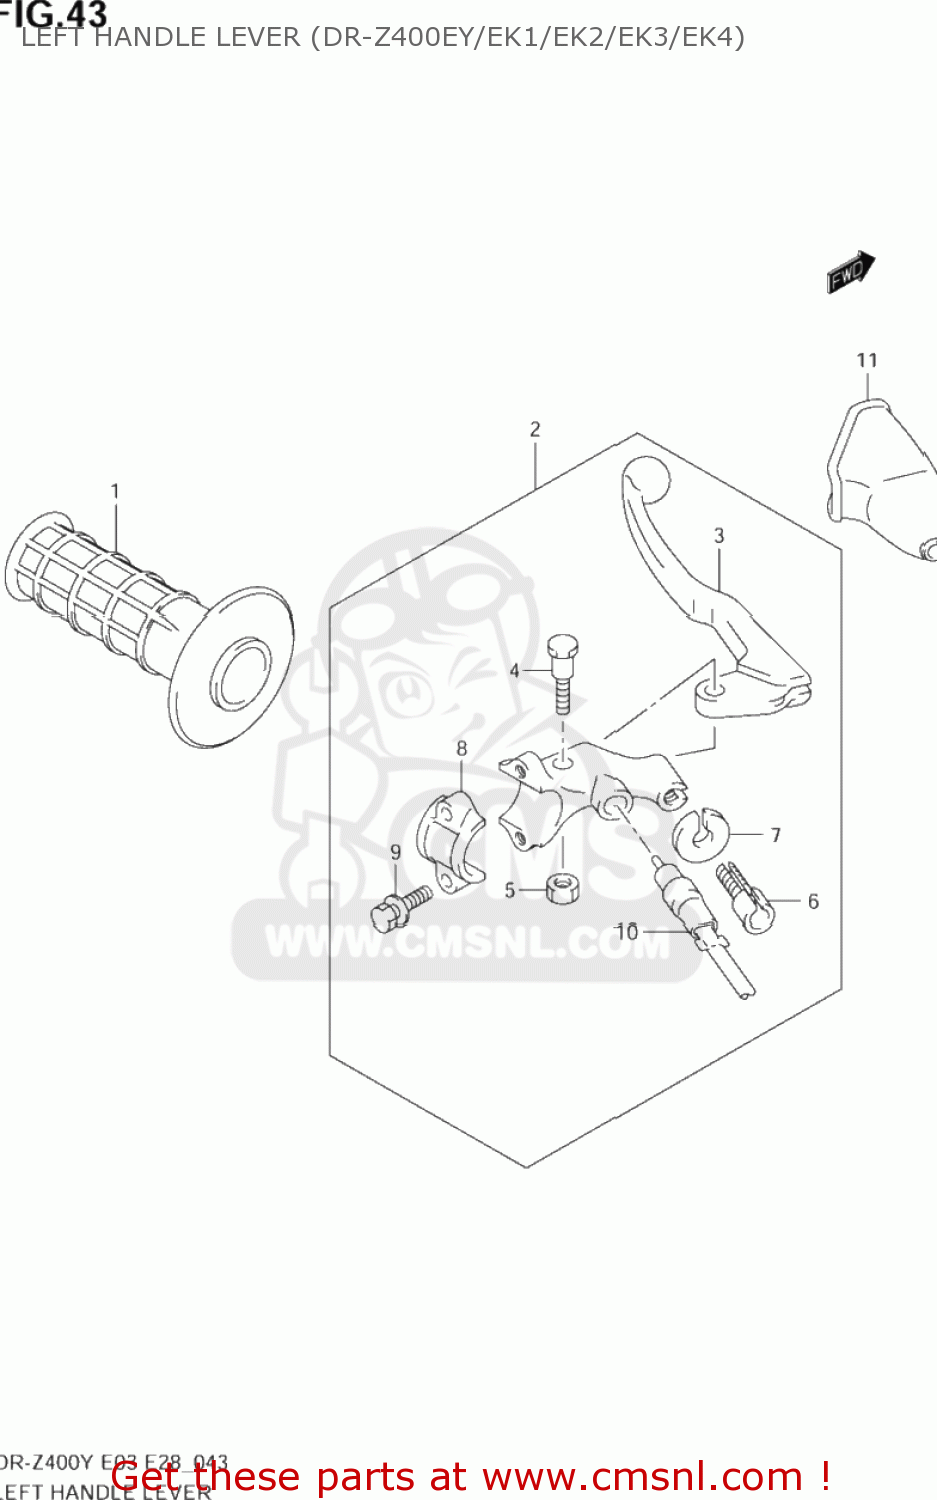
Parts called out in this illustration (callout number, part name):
1	GRIP,L
2	LEVER ASSEMBLY,CLUTCH
3	LEVER,CLUTCH
4	BOLT,LEVER PIVOT
5	NUT 6MM
6	ADJUSTER,WIRE
7	NUT,LOCK
8	BRACKET,HOLDER
9	BOLT,BRACKET
10	SWITCH ASSEMBLY,CLUTCH
11	COVER,CLUTCH CABLE DUST
